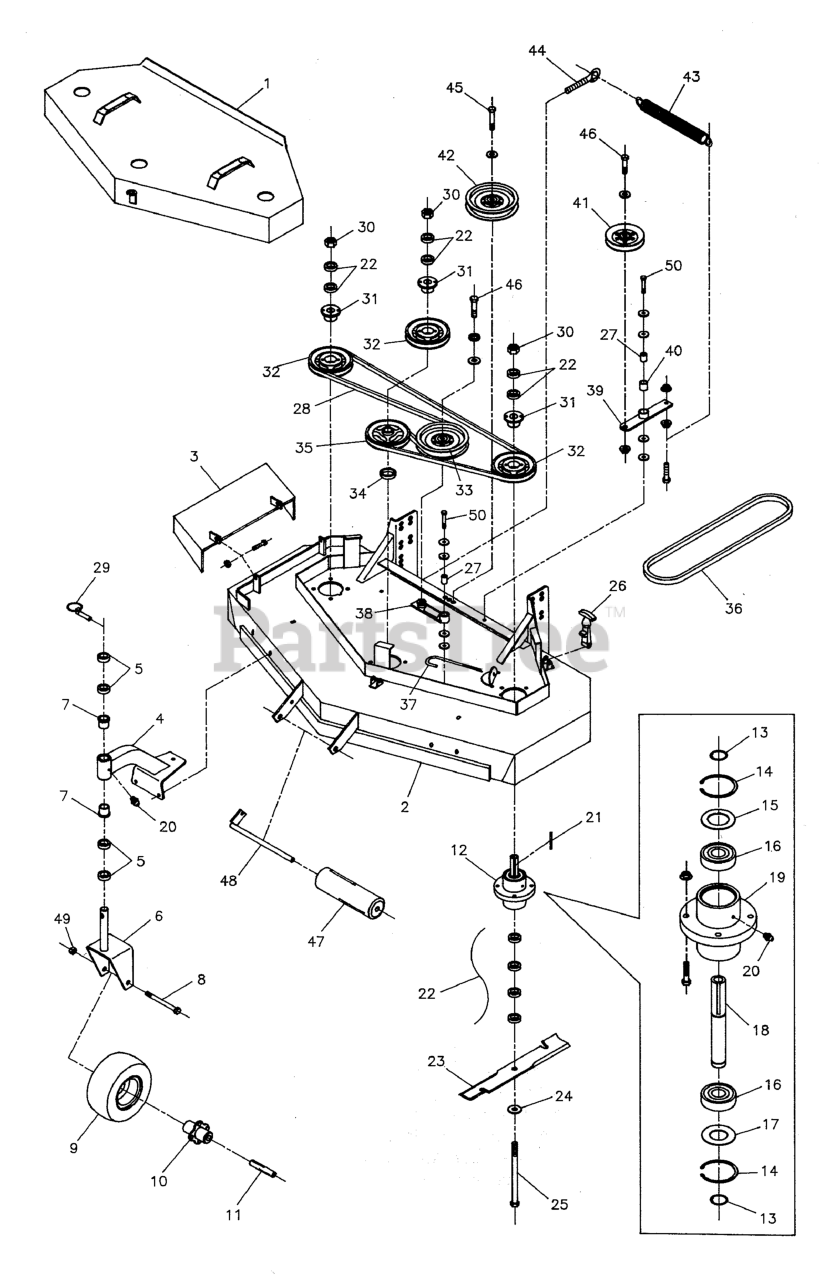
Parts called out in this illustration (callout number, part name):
1	52" GUARD
2	52" MOWER HOUSING ASSEMBLY
3	CHUTE, DISCHARGE WELDMENT
4	Caster Support (Weld. Only)
4	CASTER MOUNT, Complete
5	SPACER, 1.02 x 1.56 x .50
6	YOKE, Caster
7	BUSHING, Flange
7	Plastic Bushing
8	BOLT, 1/2-13 x 5-1/2
9	TIRE ASSM, Solid Rubber, 9 X 3.5
9A	WHEEL & TIRE ASSEMBLY, White, 9 x 3.5 x 4, Complete
9A	TIRE, Front, 9 x 3.5 x 4
9A	HUB & BEARING ASSEMBLY, Complete, White
10	4 BOLT HUB W/ BEARING
11	AXLE, Caster Wheel
12	SPINDLE ASSEMBLY, Complete
13	SNAP RING, External
14	SNAP RING, Internal
15	SPINDLE WASHER, Top
16	BEARING
17	SPINDLE WASHER, Bottom
18	SPINDLE SHAFT
19	SPINDLE HOUSING
20	GREASE FITTING
21	KEY, 1/4 SQ. X 2-1/2
22	SPACER, .63 x 1.06 x .23
23	MOWER BLADE, 18"
24	WASHER, 5/8" USS
25	BOLT, 5/8-11 x 9-1/2
26	RUBBER LATCH
27	SPACER, .32 x .75 x 1.06
28	BELT, Blade Spindle
29	PIN, Lynch
30	NUT, 5/8-11 Hex
31	BUSHING, Tapered Hub
32	PULLEY, Spindle
32	PULLEY, Split Steel
33	PULLEY, Backside Idler
34	SPACER, 1.00 X 1.25 X .25
35	SPINDLE PULLEY
35	PULLEY, Split Steel
36	Deck Drive Belt
38	IDLER ARM
39	IDLER ARM, Complete
40	BUSHING, Brass
41	PULLEY, V-Idler
42	PULLEY, Backside Idler
43	SPRING, Extension
44	EYEBOLT
45	BOLT, 1/2-20 X 2-1/2" GD5 CZ
46	BOLT, 1/2-20 X 2-1/4 GD5 CZ
47	ROLLER
49	NUT, 1/2-13 HEX NYLON LOCK
50	BOLT, 5/16-18 x 1-3/4
